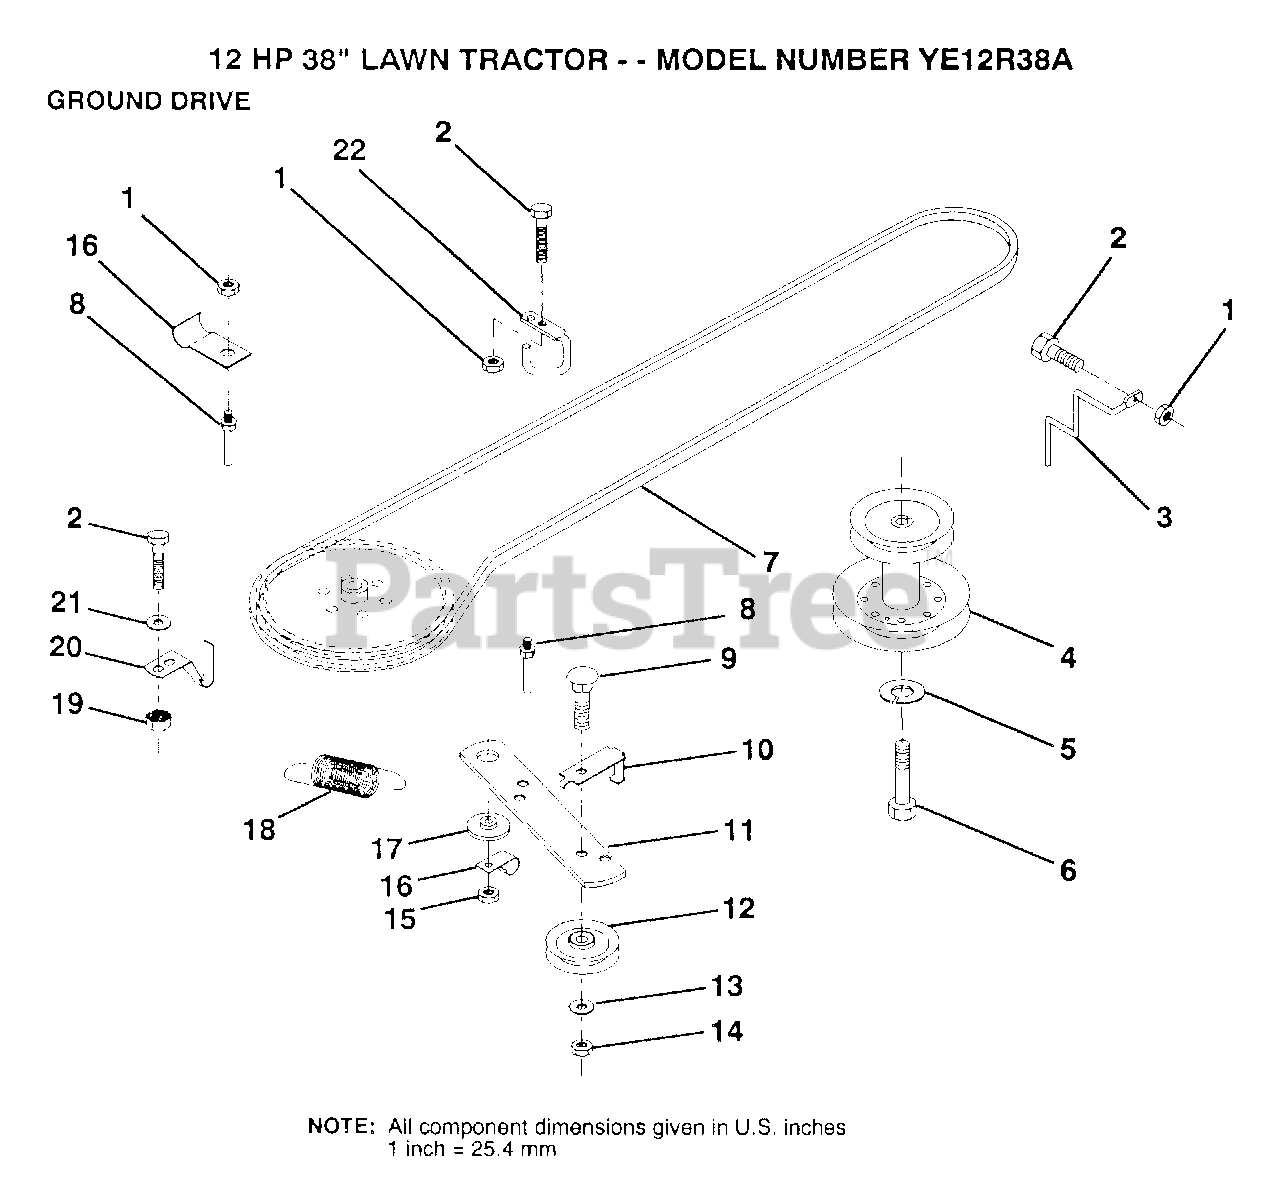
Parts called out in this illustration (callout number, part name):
2	BOLT
3	KEEPER MWR DR BLT
5	LOCKWASHER
6	BOLT
7	BELT
8	"KEEPER,DRIVE BELT"
9	BOLT
10	"KEEP,IDLER DR BEL"
13	WASHER
14	LOCKNUT
16	"CLIP,INSULATOR"
17	SPACER RETAINER
20	"KEEPER,DR BELT "
21	WASHER
22	"KEEPER,FRA DR BEL"
